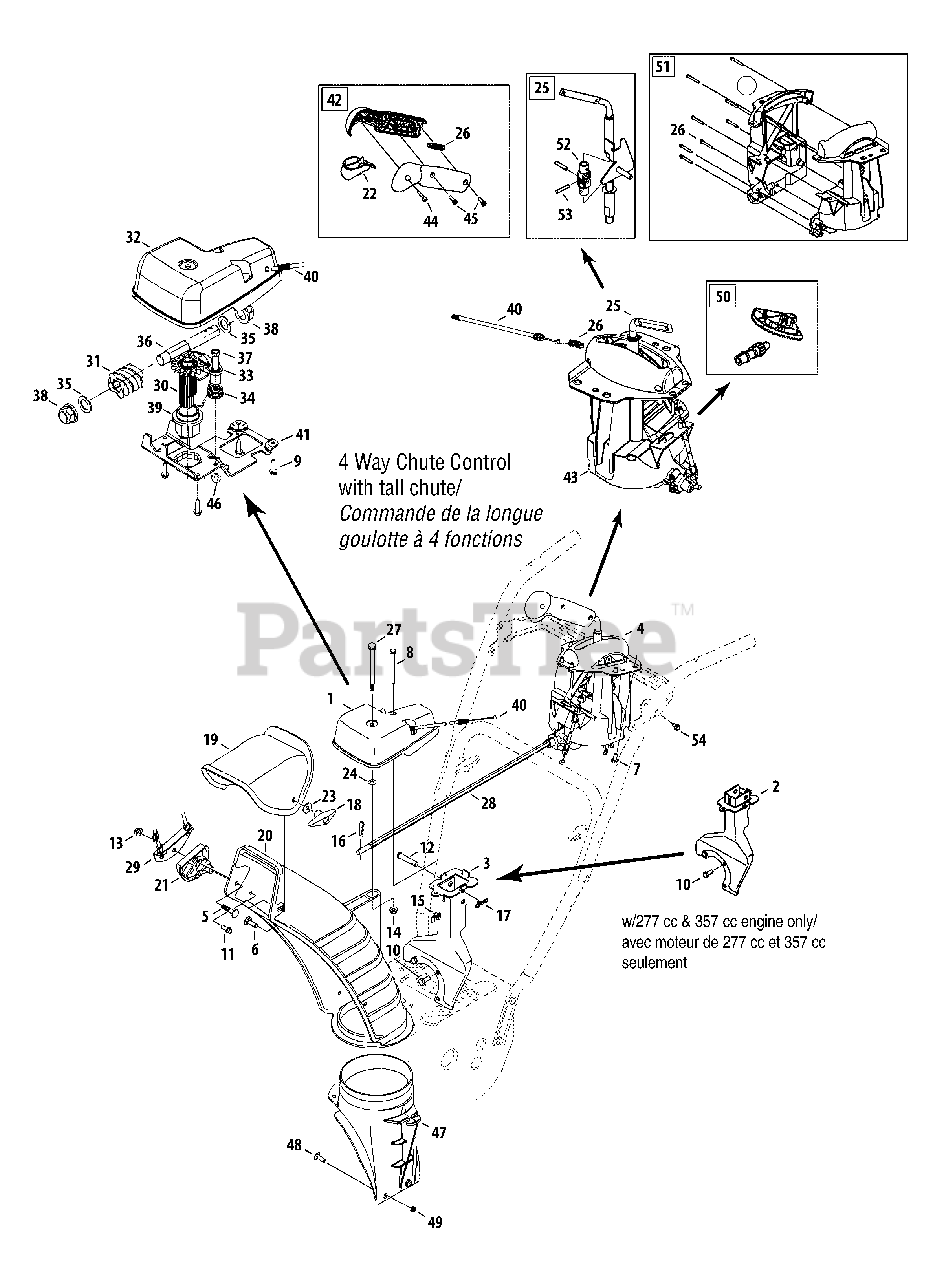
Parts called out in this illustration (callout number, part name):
1	Gearbox Assembly (4-way)
2	Chute Sup. Bkt. Ass'y
3	Chute Support Bracket Ass'y
4	4 Way Chute Control Assembly
5	Carriage Bolt 5/16-18 x 1.50 Gr. 2
6	Carriage Screw 5/16-18 x 1.0
7	Hi-Lo Screw 1/4-15 x .5
8	Hex. Hd. Cap Scr. 1/4-20 x 3.0 Gr. 5
9	Hi-Lo Screw #12-16 x .75
10	Hex Hd. Cap Screw 5/16-24 x .75
11	Hex Tapp Scr 1/4 x .75" Lg.
12	Clevis Pin 3/8 x 1.87
13	Flange Locknut 5/16-18 Gr. F Nylon
14	Hex L-Flanged Nut 1/4-20 Gr. F Nylon
15	Wing Nut 1/4-20
16	Internal Cotter Pin
17	Bow Tie Cotter Pin
18	Handle Knob Assembly
19	Upper Chute w/Export Label, Remote
22	Joystick lever trigger
23	Flat Washer .349 ID x .879 OD x .063
24	Flat Washer .25 ID x .63 OD x .0515 HT.
26	Plunger joystick
27	Flg. Shoulder Screw .312 x 3.5: 1/4-20
28	Chute Crank Rod
30	Gear 14 teeth helical w/hub
31	Worm Gear
33	Lock Pawl (4 way)
34	Torsion Spring LH .72 ID x .474
35	Flat Washer .625 x 1.0 x .067
36	Hex Shaft .625 Worm Drive
37	Shoulder Screw .340 x .950: 1/4-28
38	Hex Flg. Bearing
39	Flg. Brg. 1.0" ID
40	Trigger Lock Cable
41	Chute Gear Rotation Bracket
43	Chute Control Ass'y (4 way)
44	Screw #8: 1.0
45	Mach. Scr. #8-32 x .75
46	Hex Ins Jam L-Nut 1/4-28
47	Chute Adapter
48	Carriage Screw 1/4-20 x .75 Gr. 5
49	Hex L-Flanged Nut 1/4-20 Gr. F Nylon
50	Gear Set Assembly
51	Handle Housing Assembly
52	JointBlock Assembly
54	Hex Wash S-Tapp Scr 1/4-20 x .50
